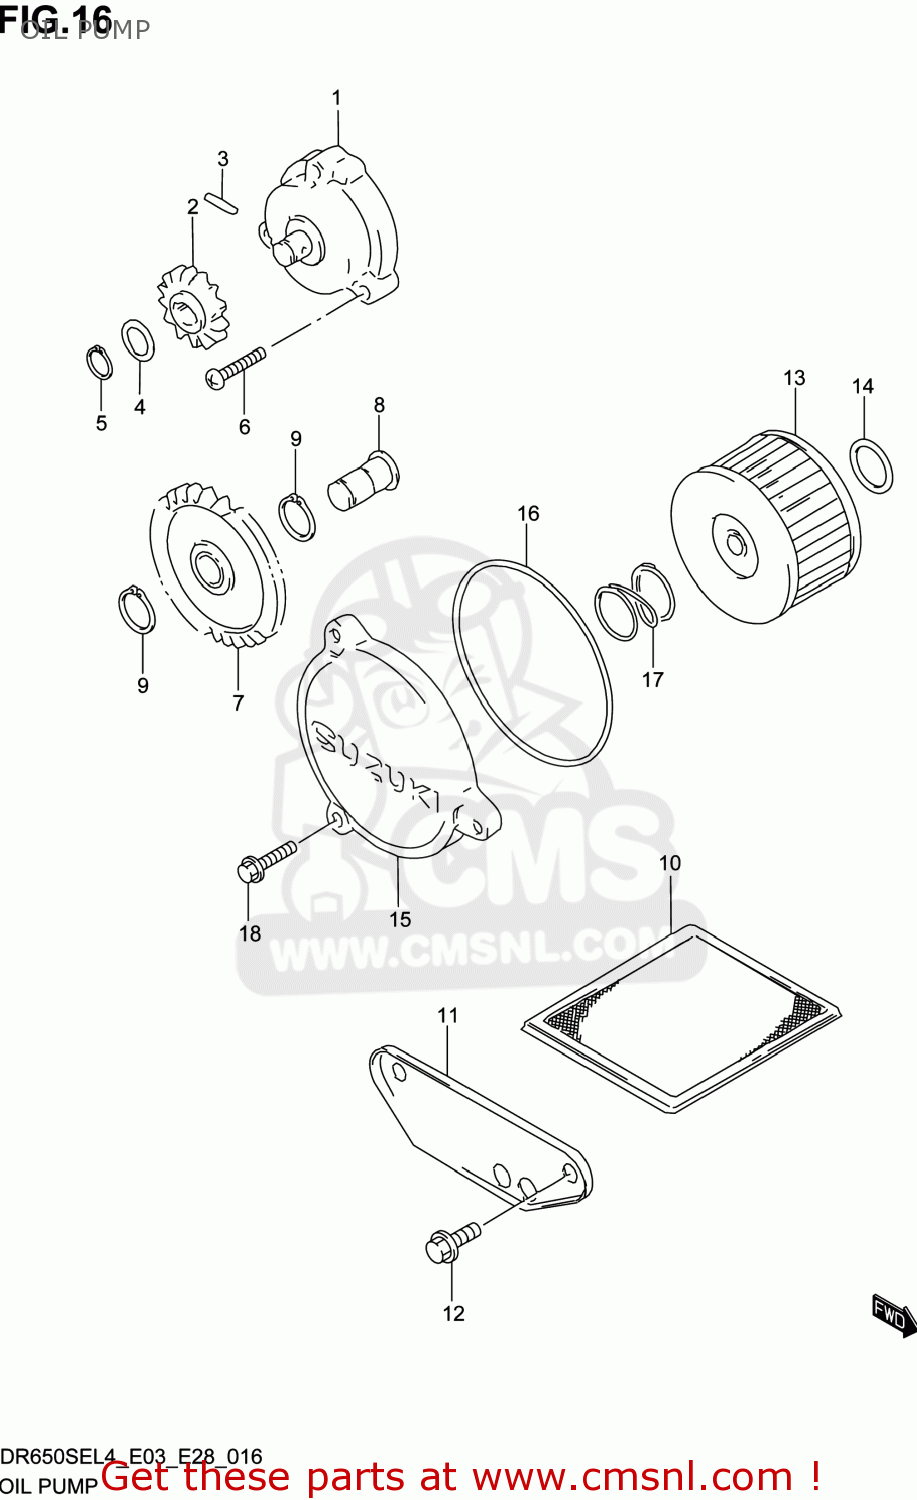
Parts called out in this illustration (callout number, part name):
1	PUMP ASSY,ENGINE OIL
2	GEAR,ENG OIL PUMP DRIVEN
3	PIN(4X15.8)
4	SHIM(10X20X0.5)
5	CIRCLIP
6	SCREW
7	GEAR,OIL PUMP DRIVE(NT:30)
8	SHIFT,ENG OIL PUMP DRIVE GEAR
9	CIRCLIP
10	STRAINER,ENGINE OIL
11	CAP,OIL STRAINER
12	BOLT(6X12)
13	FILTER ASSY,ENGINE OIL
14	O RING(D:2.4,ID:15.8)
15	CAP,OIL FILTER
16	O RING(D:2.4,ID:73)
17	SPRING
18	BOLT
